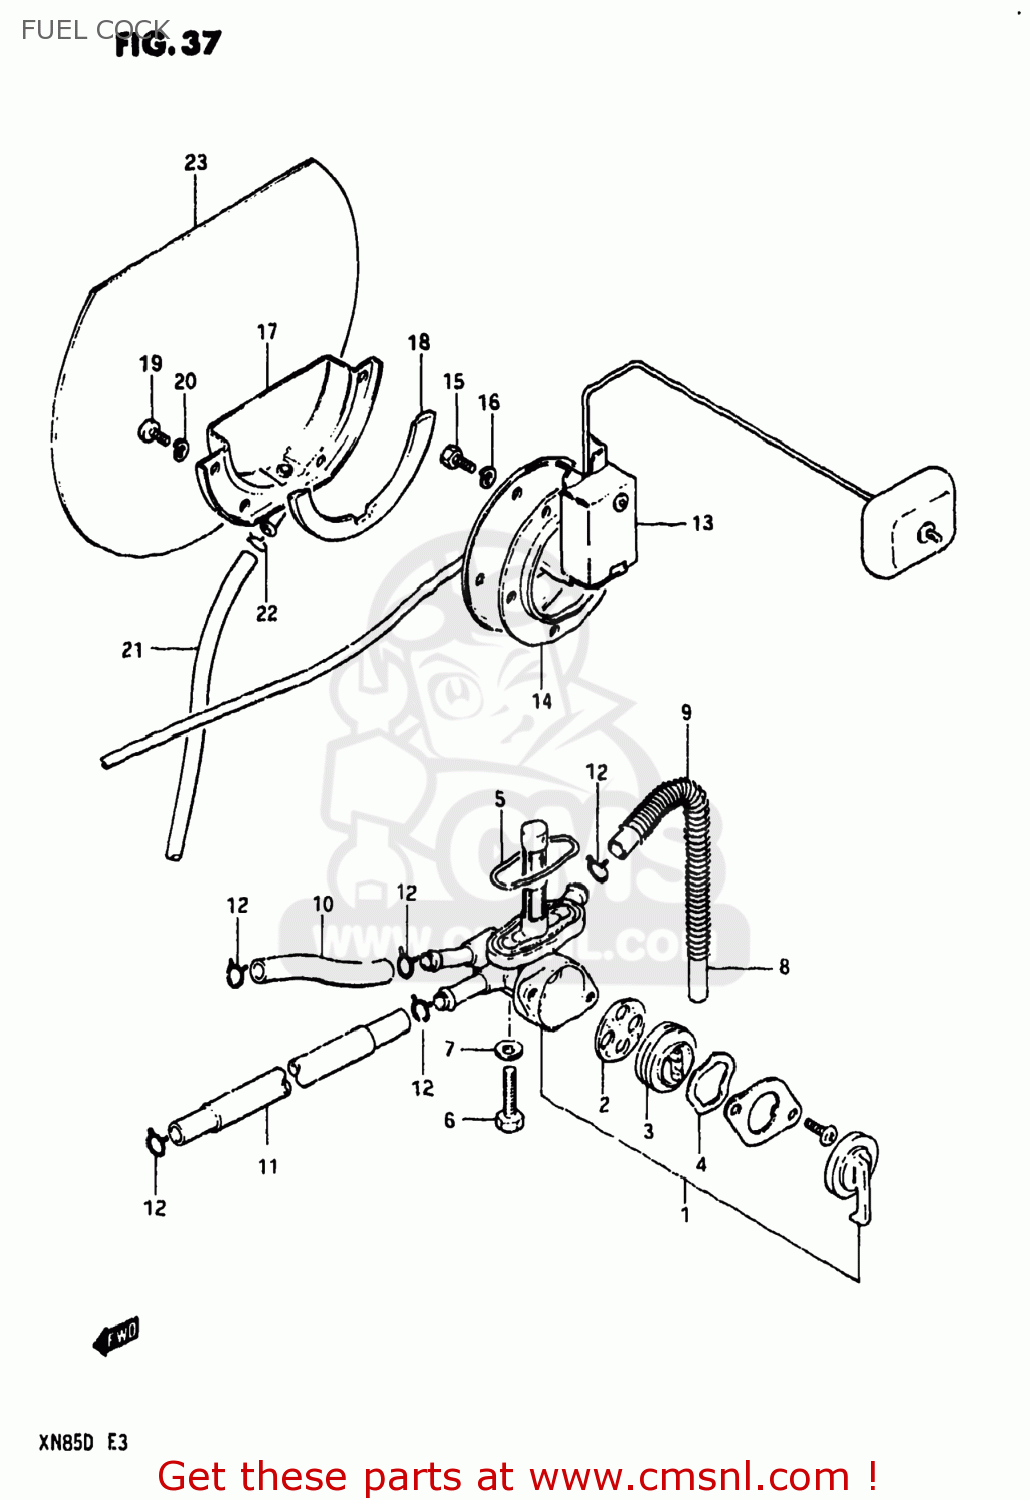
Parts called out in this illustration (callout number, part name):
1	COCK ASSEMBLY,FUEL
2	GASKET,FUEL COCK
3	VALVE,FUEL COCK
4	WASHER, LEVER
5	GASKET,FUEL COCK
6	BOLT(6X20)
7	GASKET
8	HOSE
9	SPRING
10	HOSE
11	HOSE
12	CLAMP
13	GAUGE ASSEMBLY,FUEL LEVEL
14	GASKET,FUEL LEVEL GAUGE (NAS)
15	BOLT
16	LOCK WASHER
17	PLATE,FUEL DRAIN
18	GASKET (NAS)
19	SCREW
20	LOCK WASHER
21	HOSE,FUEL
22	CLIP
23	PROTECTOR, FUEL LEVEL GAUGE
